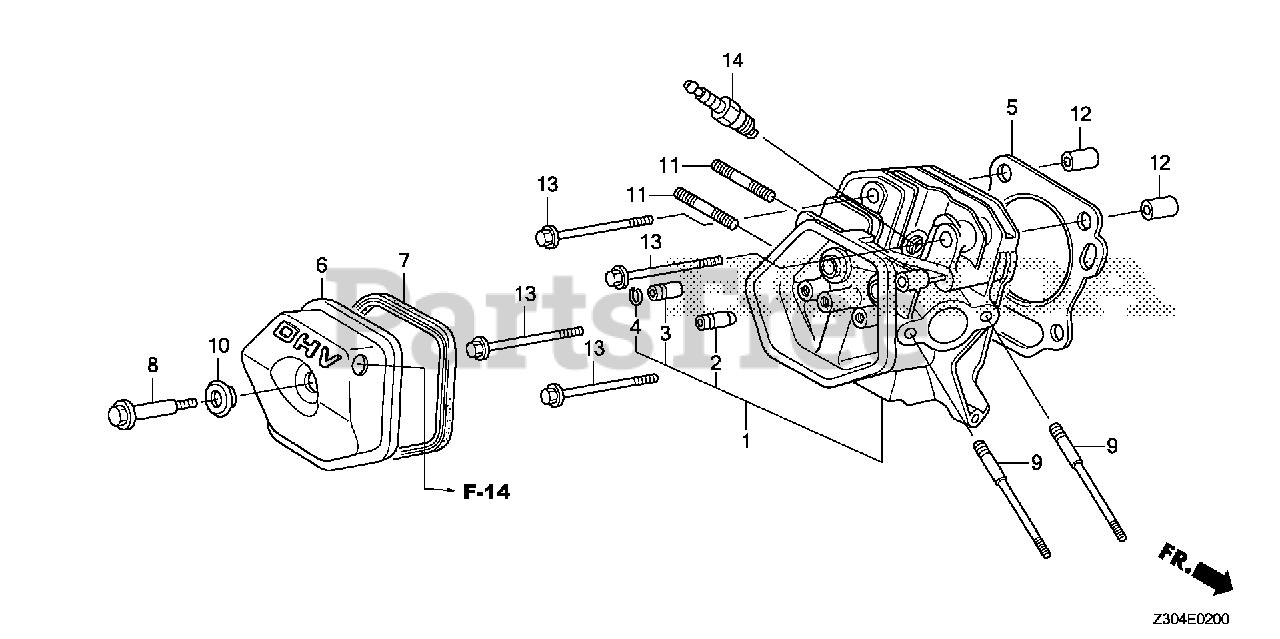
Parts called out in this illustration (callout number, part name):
1	CYLINDER HEAD
2	GUIDE, VALVE (OS)
3	GUIDE, EX. VALVE (OS)
4	CLIP, VALVE GUIDE
5	GASKET, CYLINDER HEAD (NIPPON LEAKLESS)
6	COVER, HEAD
7	GASKET, CYLINDER HEAD COVER
8	BOLT, HEAD COVER
9	BOLT, STUD (8X115)
10	WASHER, HEAD COVER
11	BOLT 2, STUD (8X32)
12	PIN A, DOWEL (12X20)
13	BOLT, FLANGE (10X80)
14	SPARK PLUG (BPR5ES) (NGK)
